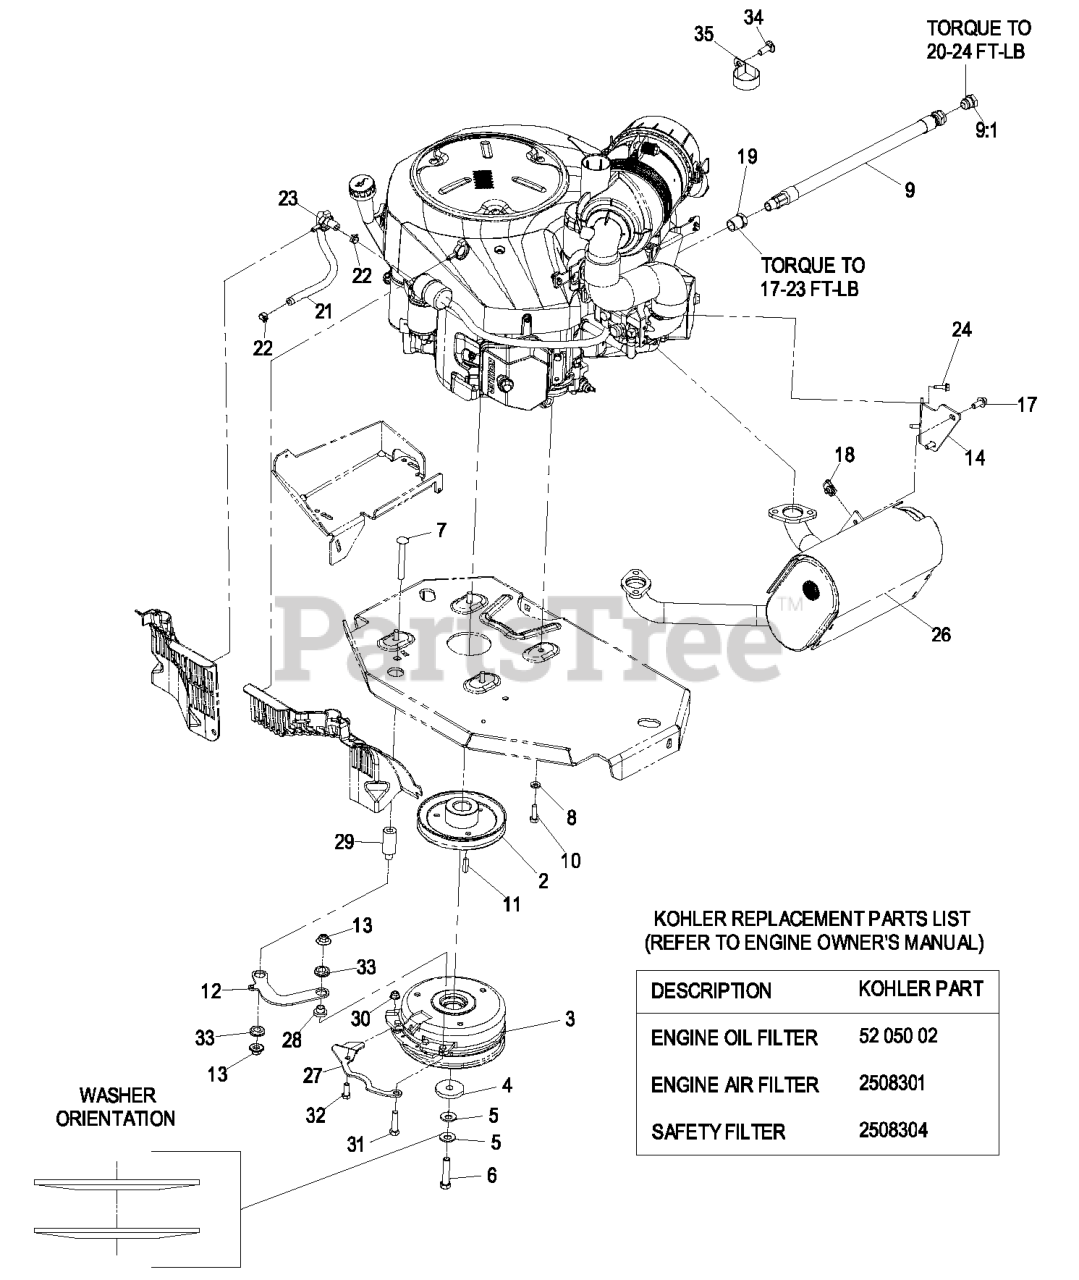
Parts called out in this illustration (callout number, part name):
2	SHEAVE
4	WASHER-CLUTCH
5	WASHER-SPRING
6	SCREW-HH W/LOCTITE
7	SCREW-CARR
8	WASHER-SPRING
10	SCREW-HH
12	LINK-ANCHOR, CLUTCH
13	Nut-Nyloc 3/8-16 Flg
17	SCREW-HHF
19	BUSHING
22	CLAMP-HOSE
23	CLAMP-HOSE
26	MUFFLER
27	BELT-GUIDE
30	NUT-HF, NI
31	SCREW-HH
32	SCREW-HH
33	GROMMET-RUBBER
34	SCREW-CARR
35	CLAMP-R
